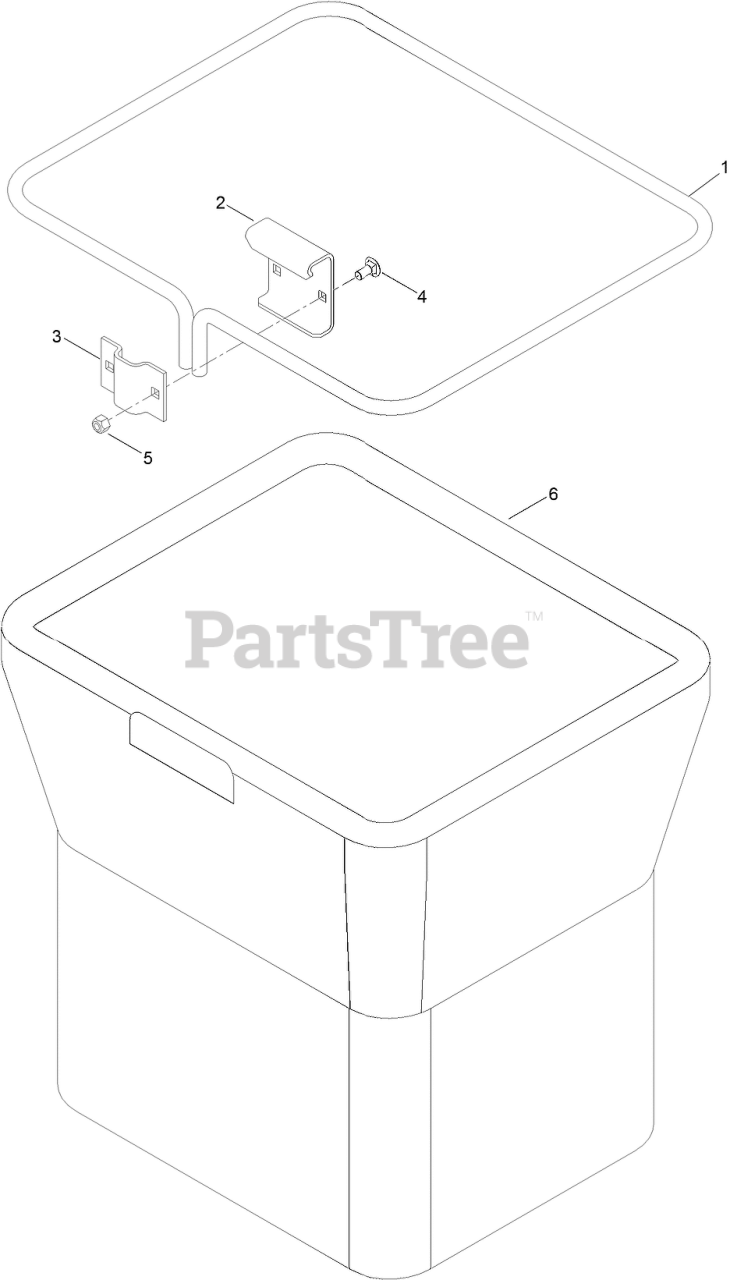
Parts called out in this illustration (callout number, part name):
1	FRAME-BAG
2	HANGER-BAG
4	BOLT-CARR
5	NUT-LOCK, NI
